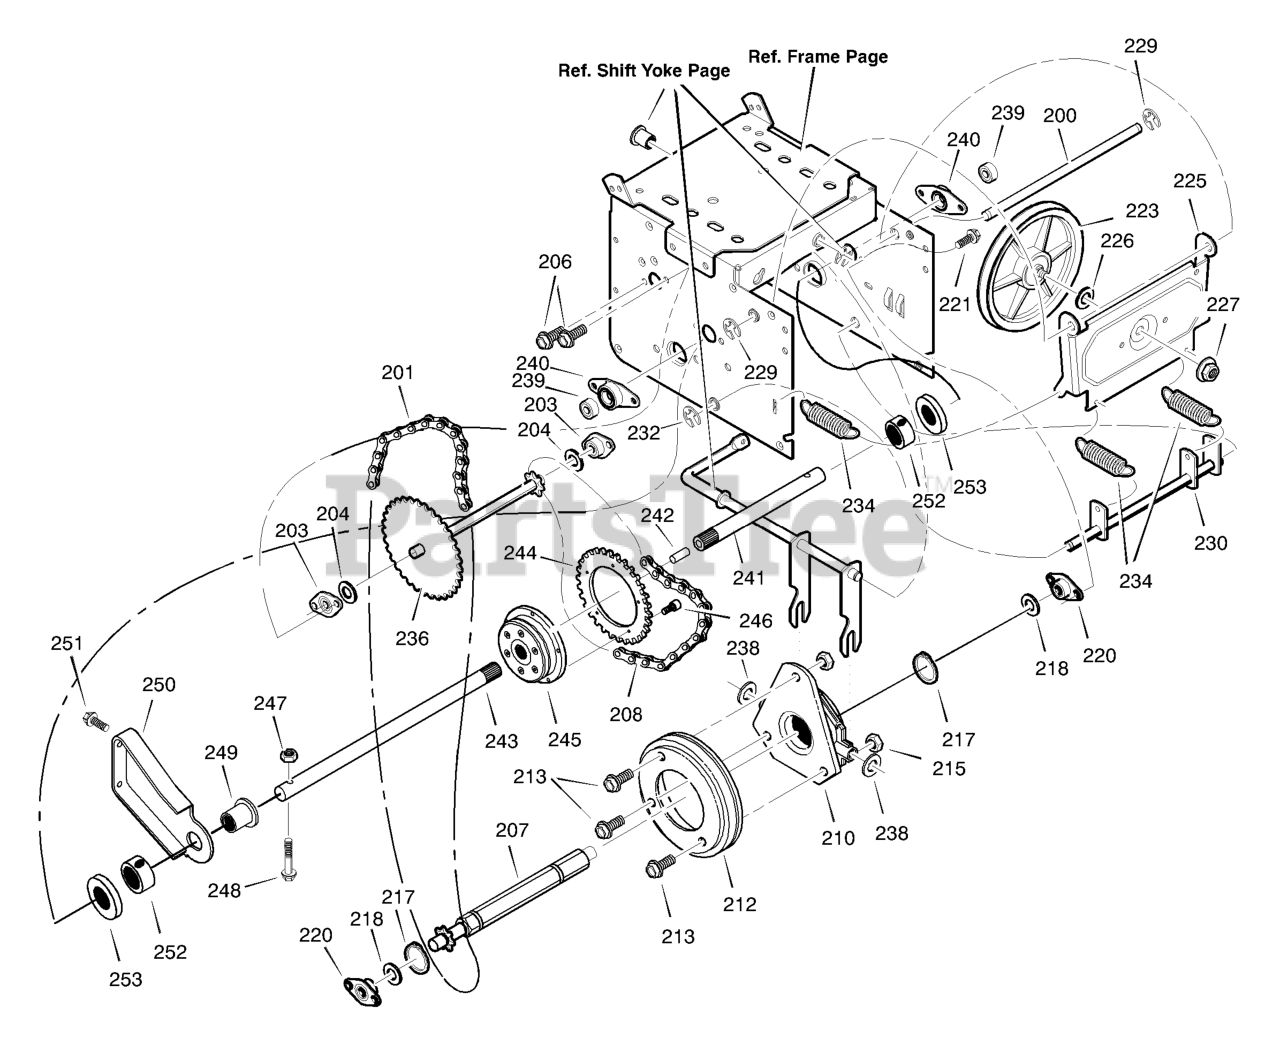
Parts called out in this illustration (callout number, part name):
200	LF AXLE, SWING PLATE YZ
201	CHAIN, ROLLER #420x19.00
203	BEARING AND RETAINER, ASSY
206	SCREW, TAP 5/16-18 x 0.5
207	ASSY, HEX SHAFT
208	CHAIN, ROLLER #420x18.00 LG
210	BEARING, TRUNION CLUTCH R
212	WHEEL, FRICTION DISC
215	NUT, KEPS HEX 1/4-20
217	RING, RETEXT
220	BEARING AND RETAINER, ASSY
221	SCREW, TAP 5/16-18 x .5
223	FRICTION PULLEY
225	LF PLATE, SWINGING YZ
226	SPACER, FRICTION PULLEY
227	NUT, FLANGE LOCK 3/8-24
229	RETAINER, RING
230	ASSEMBLY, SPRING LINK STEERABLE
232	RETAINER, RING
234	SPRING, EXTENSION
236	SPROCKET SET 33T/7
238	WASHER, FLAT
239	BEARING, BALL
240	RETAINER, BEARING
241	AXLE AND BUSHING, LEFT
242	PIN, AXLE
243	AXLE AND BUSHING, RIGHT
244	SPROCKET
245	CLUTCH, AUTO LOCK
247	NUT
248	BOLT
249	BEARING, AXLE
250	BRACKET, AXLE SUPPORT
251	SCREW
252	COLLAR, LOCKING
